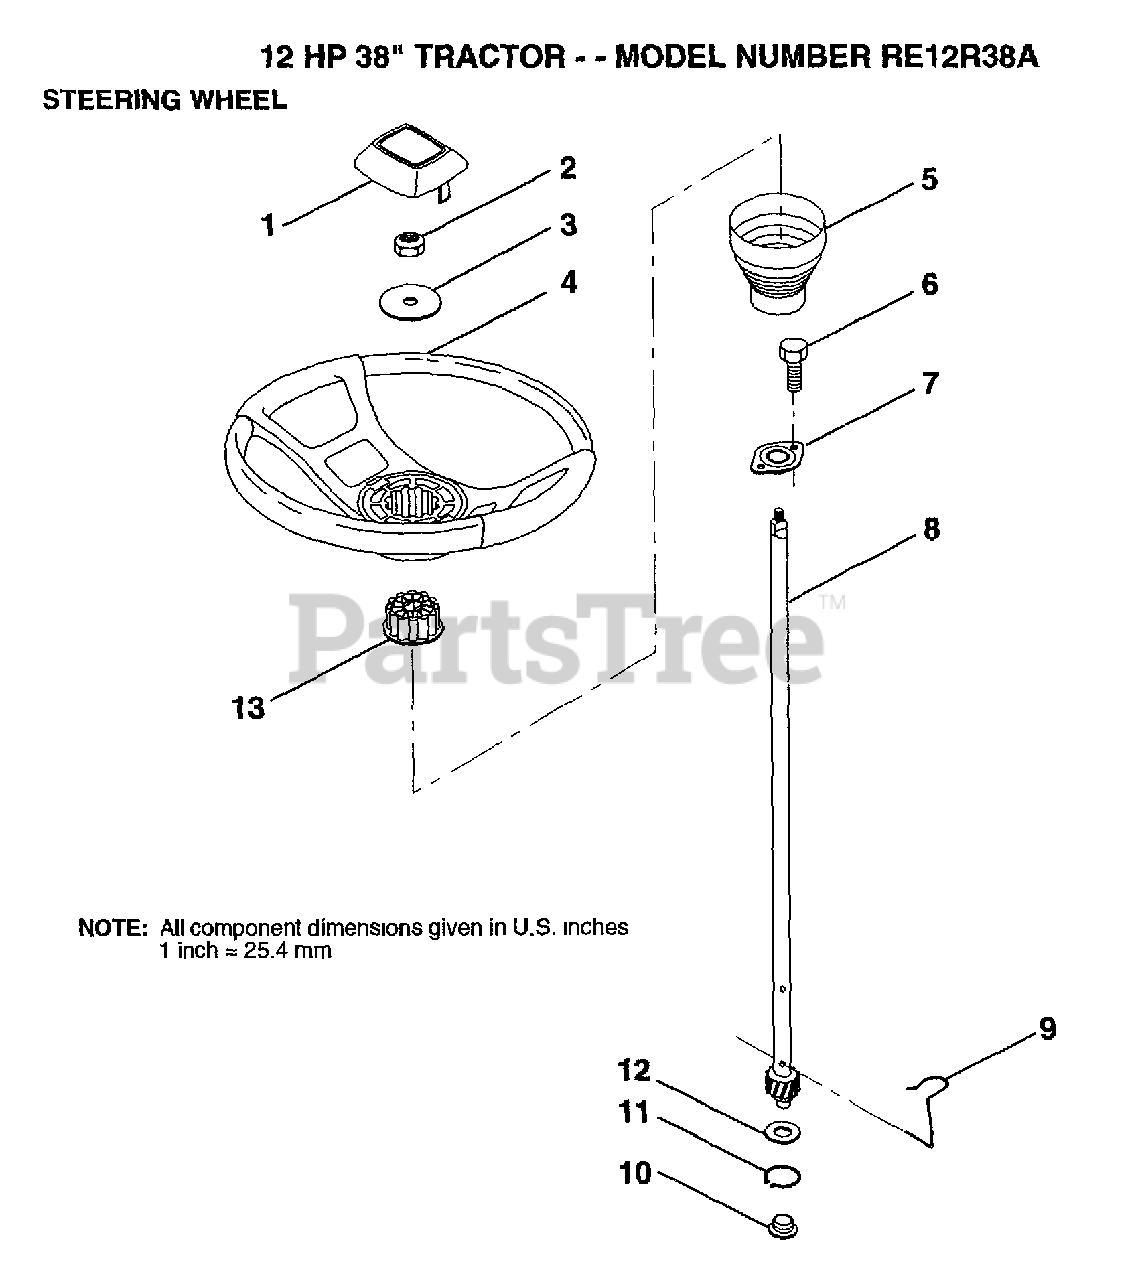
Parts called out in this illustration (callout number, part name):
2	GRIPCO NUT
3	WASHER T
5	SLEEVE STEERING
9	STEERING CLIP
10	BUSHING STEER LWR
11	RING
12	WASHER LT
13	ADAPTER-WHEEL LT
